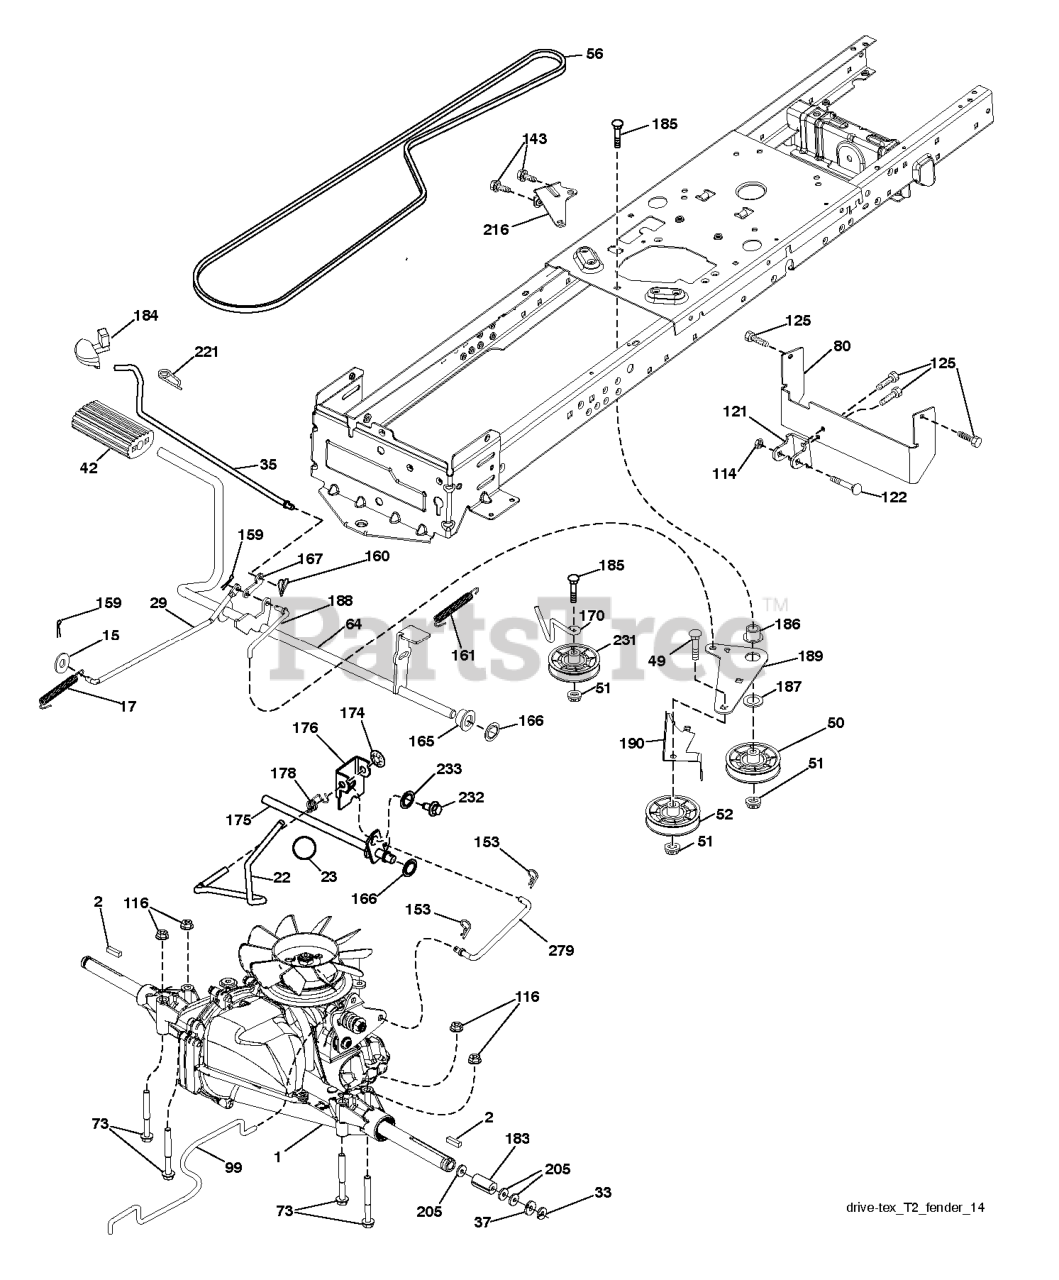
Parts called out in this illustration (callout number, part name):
2	SQUARE KEY
15	WASHER
17	SPRING.BRAKE.HG3000/3500
22	ROD.SHIFT.FENDER.TLT.2006
23	KNOB.DUCKHEAD.1/2
29	ROD.BRAKE.T2.TEX
35	ROD.CNTRL.PARK.PREDATOR.LT.TEX
42	PEDAL COVER T
50	IDLER.FLAT.910.OFFSET
51	NUT LOCK FLG 3/8-16 UNC
52	IDLER.V-GROOVE.910.OFFSET
64	SHAFT.ASM.PEDAL.BRAKE.
73	BOLT HEX 5/16-18 GR 5
80	STRAP.TORQUE.T2
99	ROD.ASM.BYPASS.SPRING.T2.FS
114	NUT.71038.31-18.HEX.NYLOCK
116	NUT LOCK HEX FLANGE 5/16-18
121	BRACKET STRAP TORQUE
122	BOLT.5/16-18X2.5
125	SCREW
143	Screw 5/16-18 x 1/2 Hex, Self Tapping 5/16-18 x 1/2
153	RETAINER M
159	COTTER PIN
160	RETAINER CLIP
161	SPRING, RETURN LT
165	BUSHING.SHAFT.BRAKE.HAND
166	NUT.PUSH.625
167	LATCH.BRAKE.SPRING
170	KEEPER.CENTER SPAN.1.688
174	NUT.PUSH.500.2006
175	SHAFT.ASM.SHFT.T2.TLT
176	ARM.CLEVIS.ROD.SHIFT
178	SPRING.SHIFT.GT2006
183	SPACER, AXLE PVST
184	HANDLE.PARKING.BRK.PRED.LT.RED
186	SPACER.RETAINER
187	WASHER 12/32X2X10GA
188	RP.LINK.CLUTCH.GROUND.DRIVE
189	BELLCRANK.GROUND.DRIVE.TEX.
190	KEEPER.BELLCRANK.DRIVE
216	BRACKET.PULLEY.IDLER.W/TEX
221	RETAINER.SPRING.CLIP.H
231	IDLER.V-GROOVE.1.688.OFFSET
232	BOLT FIN HEX 7/16-14 X 1
233	WASHER SERRATED
279	LINK.SHIFT.T2
